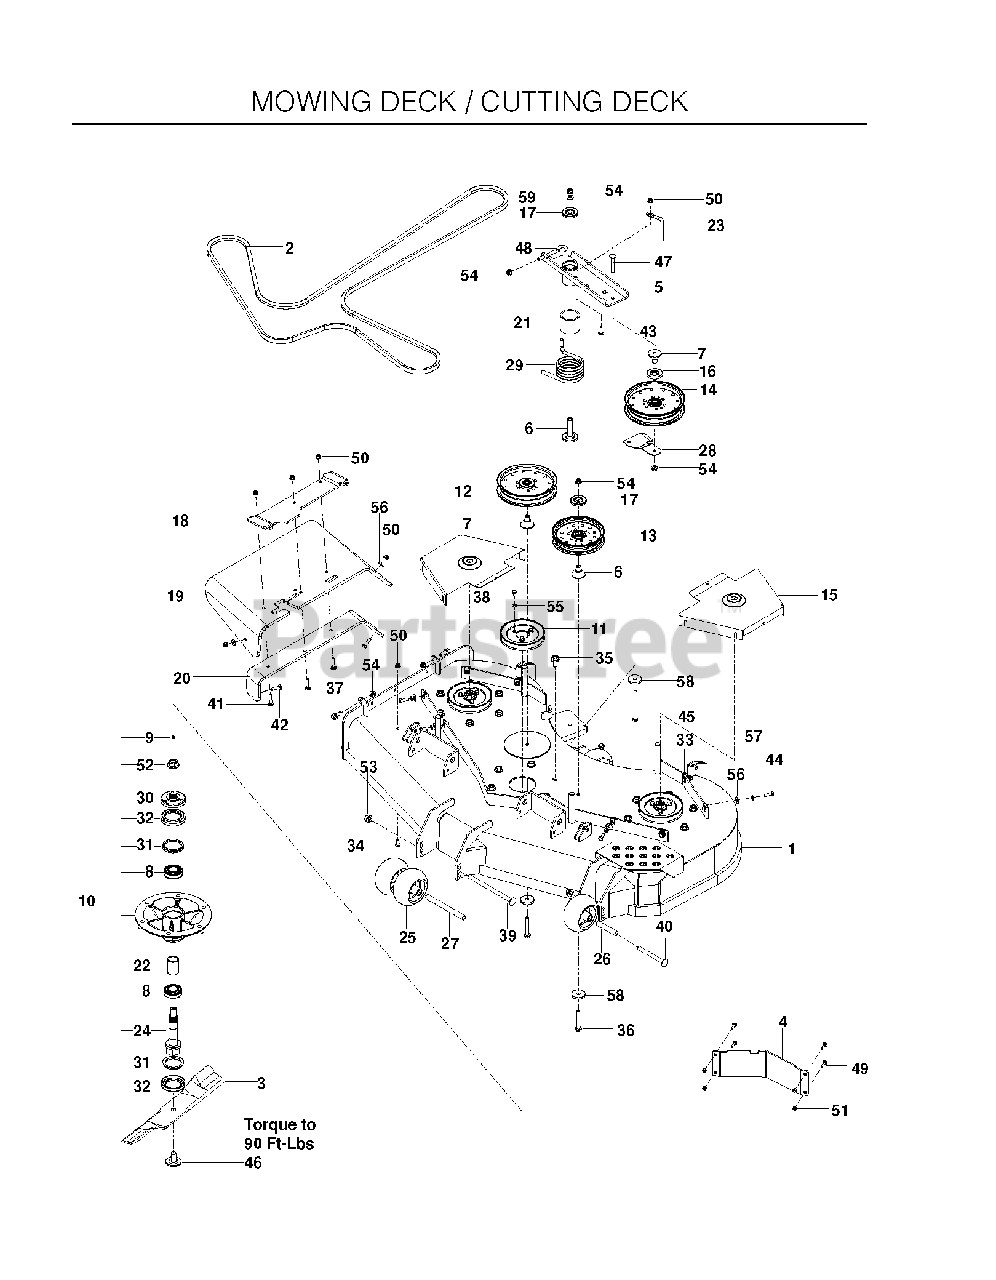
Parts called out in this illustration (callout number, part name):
1	DECK.FAB.54".W/DECALS.ORANGE
2	BELT, "B", 169.75
3	BLADE, 19"
4	BAFFLE, DIVERTER 54"/60" LH
5	ASSY, IDLER ARM, PZ
6	BEARING, IDLER PIVOT
7	BEARING, IDLER ARM
8	BEARING - 206KRR8
9	ZERK
10	SPINDLE ASM. 10"
11	PULLEY - 5.93 OVER PINS
12	PULLEY - 7" NARROW
13	PULLEY IDLER, 6" NARROW
14	PULLEY - IDLER 7"
15	SHIELD,BELT, 60" ORANGE
16	SHIELD, DUST
17	DUST SHIELD
18	BRKT - CHUTE MTG BLACK
19	CHUTE, DISCHARGE 48-52
20	BRKT, CHUTE SUPPORT BLACK
21	SPACER, IDLER PIVOT
22	SPACER - BEARING
23	BELT KEEPER
24	SHAFT - SPINDLE
25	ROLLER, GAUGE .635 BORN
26	TUBE, ROLLER AXLE
27	TUBE, ROLLER AXLE LONG
28	BELT.GUIDE.BLACK
29	SPRING, TORSION, IDLER
30	HUB - PULLEY
31	V-RING, 55MM
32	CUP - DEBRIS
33	U-CLIP 5/16-18 NUT RETAINER
34	HHFS 5/16-18 X 3/4
35	HHFS 1/2-13 X 1 GR5 ZD
36	HHFS 3/8-16 X 2 3/4
37	HHFS 3/8-16 X 1 GRD 5 ZD
38	HCS 5/16-18 X 1/2 GR 5 ZD
39	RHSNB 1/2-13 X 8 GR5 ZD
40	RHSNB 1/2-13 X 4.75 GR5 ZD
41	RHSNB 5/16-18 X 1-1/2 GR 5 ZD
42	BOLT, CARRIAGE 5/16X1-1/4
43	RHSSNB 5/16C X 1.0
44	HCS 5/16C X 1
45	HCS 3/8-16 X 4-1/2 GR 8 ZD
46	BLADE BOLT/WASHER
47	CARRIAGE BOLT 3/8-16 X
48	EYE BOLT, 3/8 X 4"
49	1/4-20X3/4 CARR BLT
50	5/16-18 NYLOC FLANGE NUT
51	RP_NUT 1/4-20 NYLOC
52	NUT FLANGE 3/4-16
53	NUT, 1/2-13 HEX FLG NYLOC ZD
54	NUT 3/8-16 HEX FLG NYLOC ZD
55	WASH 5/16 DISC SPRING ZD
56	WASHER 5/16 FLAT
57	WASHER 5/16 LOCK
58	SPINDLE WASHER
59	WASHER, 3/8 THICK
